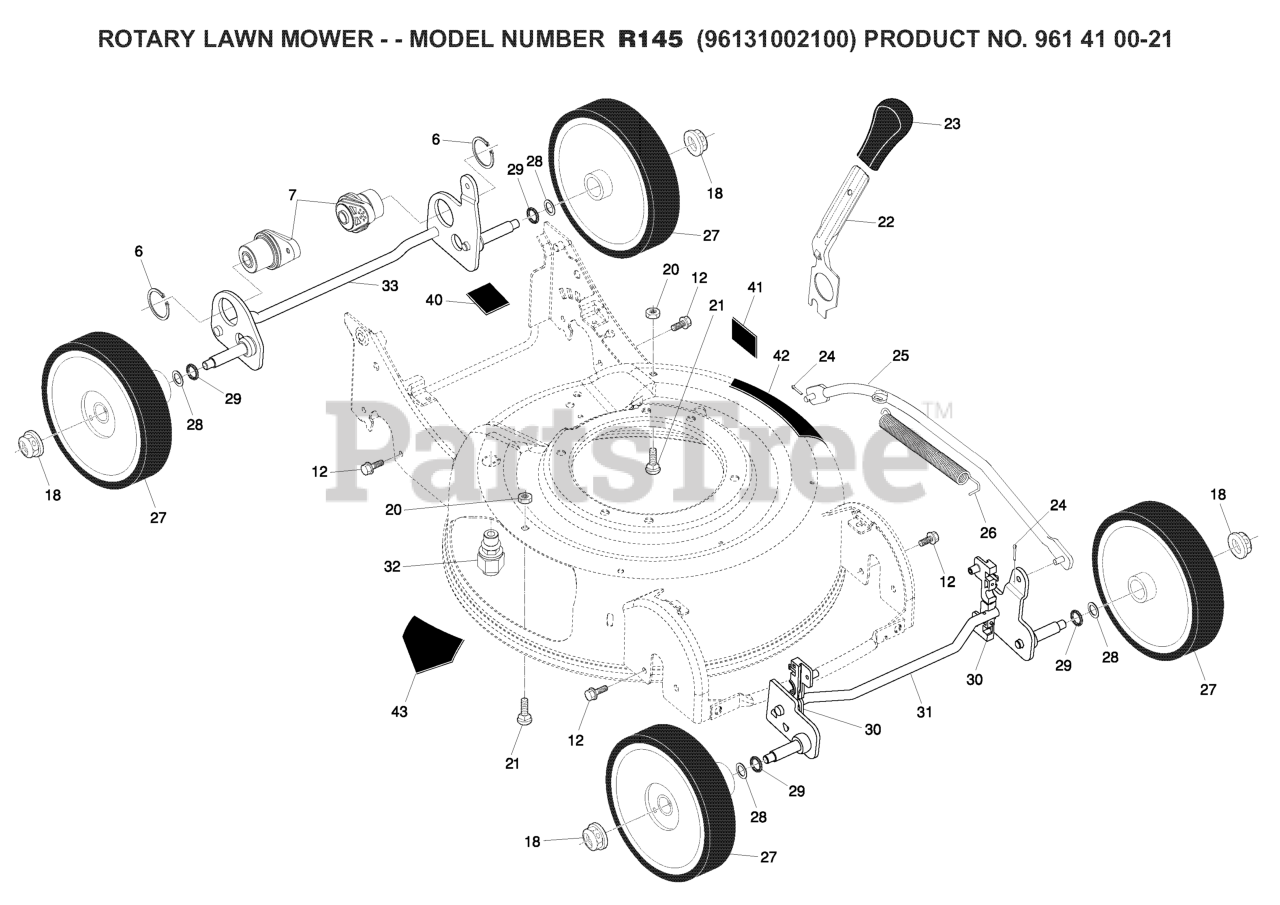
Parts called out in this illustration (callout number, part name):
6	RETAINING RING (2 2)(3 2)
18	HEX FLANGE LOCKNT
20	NUT
21	BOLT.CARRIAGE.1/4-20 X 7/8
24	RETAINER CLIP
25	KIT.ROD.LINK.REPLACE.199310
26	SPRING EXTENSION
27	WHEEL & TIRES ASSY, FRONT
28	WASHER.FLAT.1/2
29	O-RING..070X.487.NEOPRENE
30	BUSHING.FRONT.TORQUE.S
43	DECAL.INTERNATIONL.CUTFINGER
